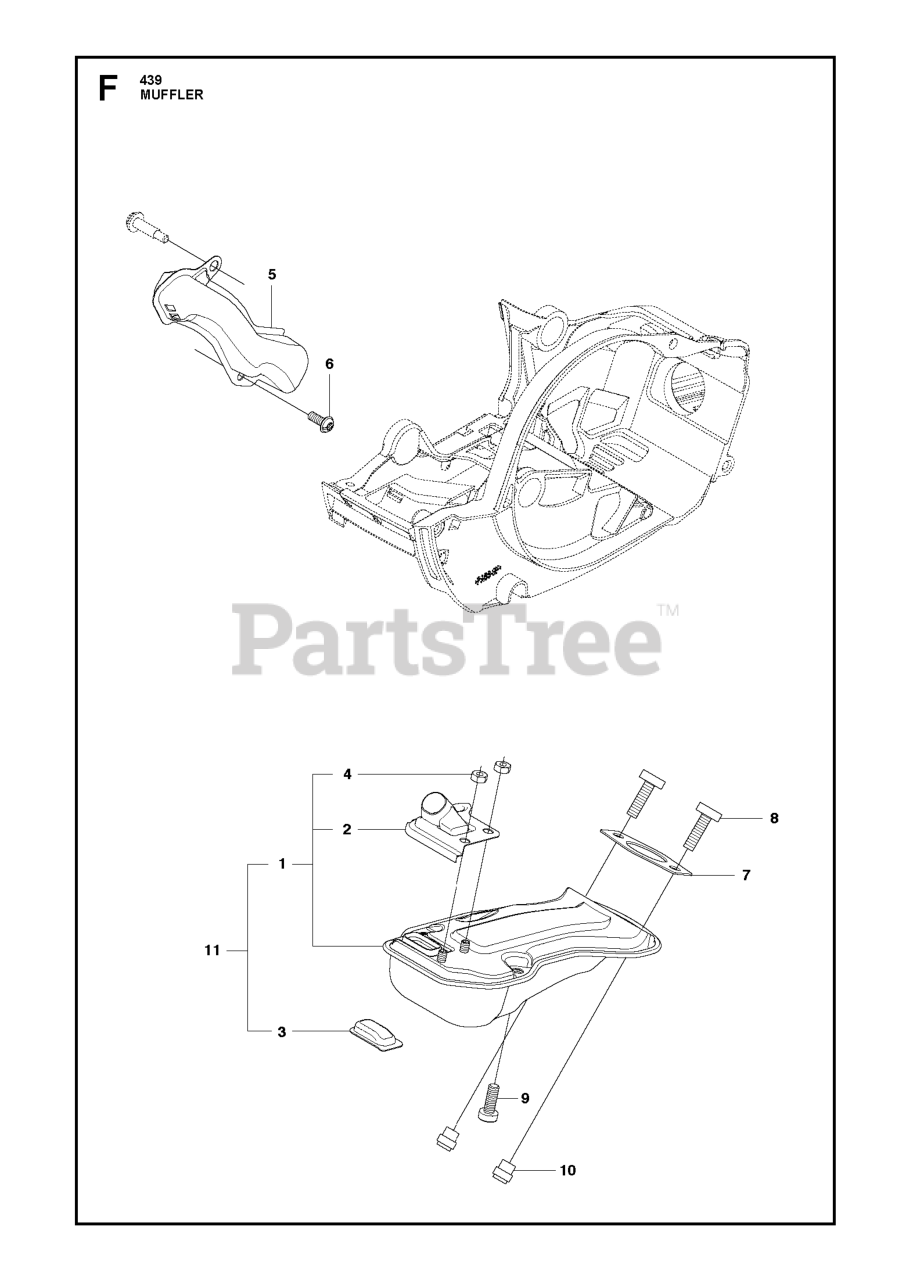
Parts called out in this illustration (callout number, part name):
1	MUFFLER ASSY
2	GUIDE, MUFFLER
3	SPARK ARRESTER
4	NUT
5	PIPE EXHAUST
6	SCREW
7	GASKET, MUFFLER
8	BOLT
9	BOLT
10	NUT
11	MUFFLER
